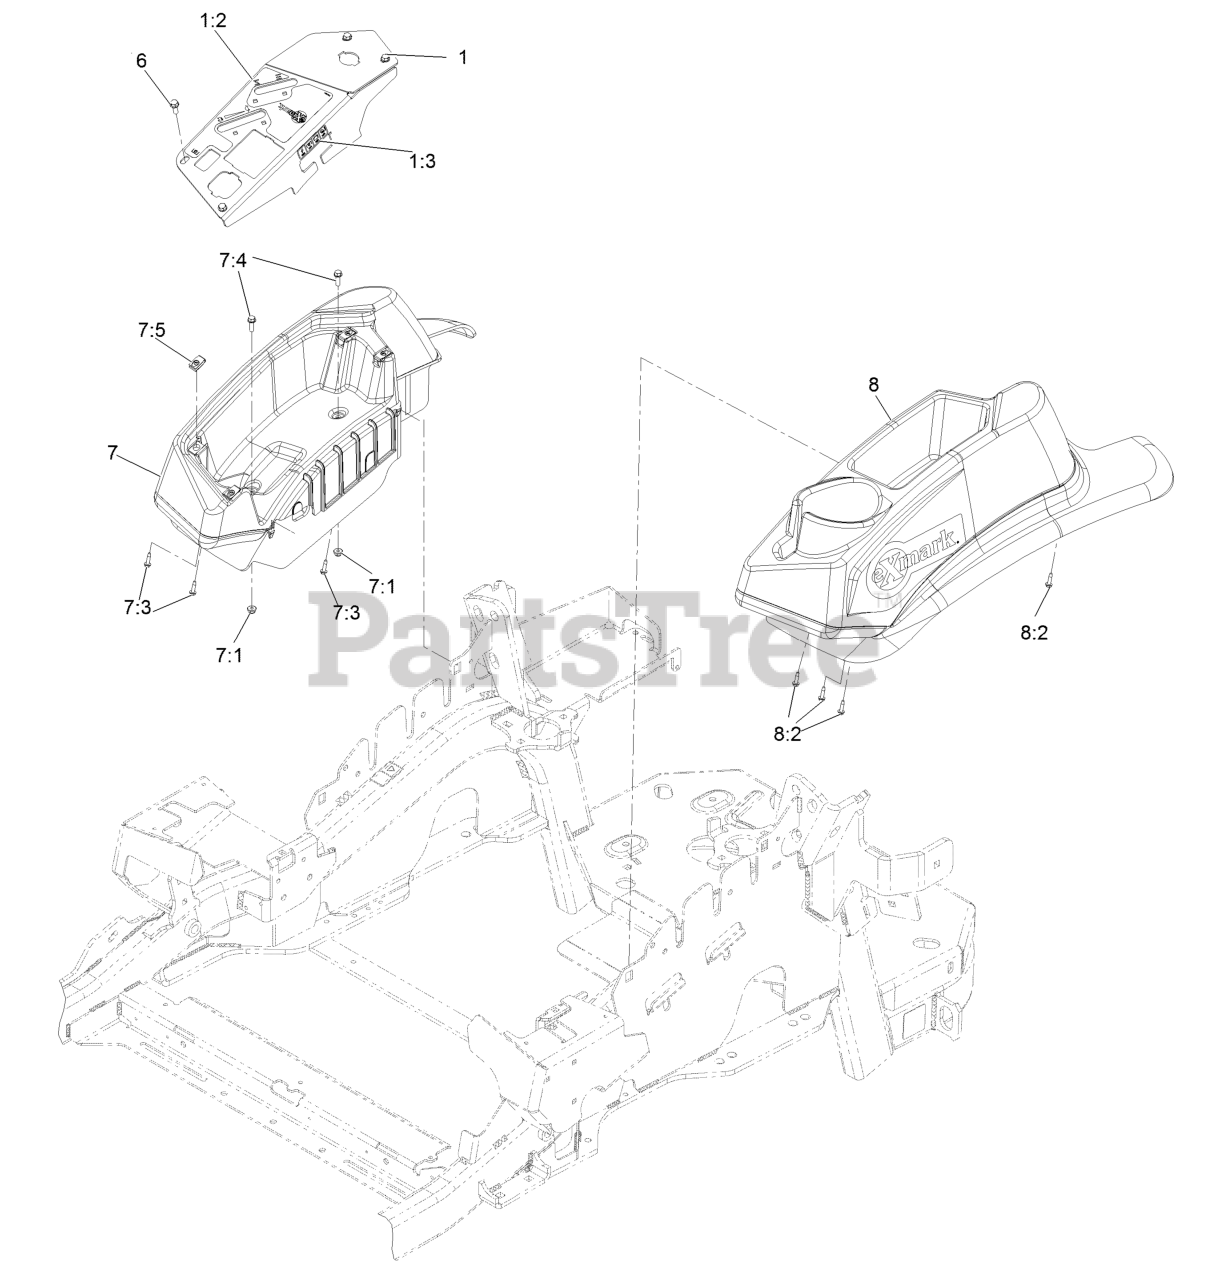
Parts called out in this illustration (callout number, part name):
1	ASM-Panel, Control W/Decal
1:2	Decal-Control Panel Non-Efi
1:3	Decal-Fuses
6	Screw-Machine 1/4-20 X 3/4
7	Console,RH Narrow ASM
7:1	Nut-Nyloc 1/4-20 Flg
7:3	Screw-HWH #10-14 X 3/4 Tf
7:4	Screw-Machine 1/4-20 X 3/4
7:5	Nut-Retainer-Panel 1/4-20
8	Console.LH Narrow ASM
8:2	Screw-HWH #10-14 X 3/4 Tf
